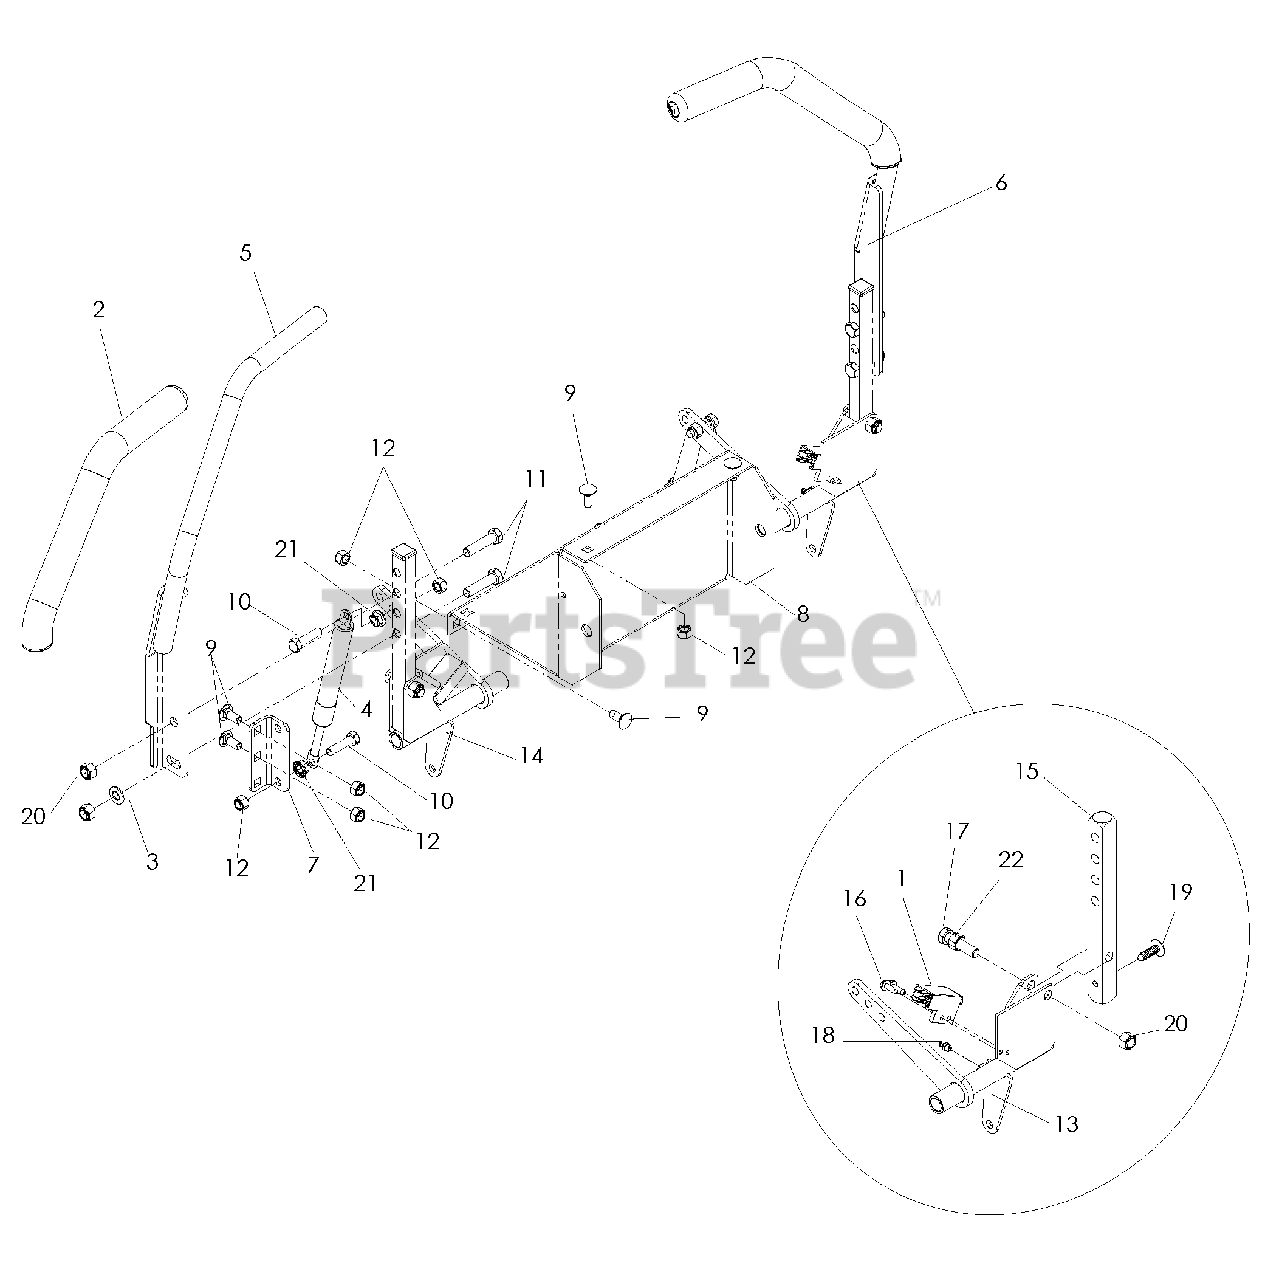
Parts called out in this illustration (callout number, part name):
1	SWITCH, INTERLOCK
2	CUSHION, DRIVE LEVER
3	LOCKWASHER 3/8 SPEC.
5	DRIVE LEVER, RIGHT
6	DRIVE LEVER, LEFT
7	DAMPENER BRACKET
8	BATTERY TRAY
9	RHSNB 5/16-18 x 3/4
10	HCS 5/16-18 x 1 1/4
11	HCS 3/8-16 x 1 1/2
12	NUT 5/16-18 NYLOC
13	CONTROL , LEFT
14	CONTROL , RIGHT
15	CONTROL ARM
16	SCREW 10-24 x 5/8 WSH HD
17	HCS 3/8-16 x 2 1/2 TPBLT
18	ZERK
19	RIVET, NYLON PUSH-IN
20	NUT 3/8-16 NYLOC
21	NUT 5/16-18 WHIZLK
22	NUT 3/8-16 CENTERLOCK
